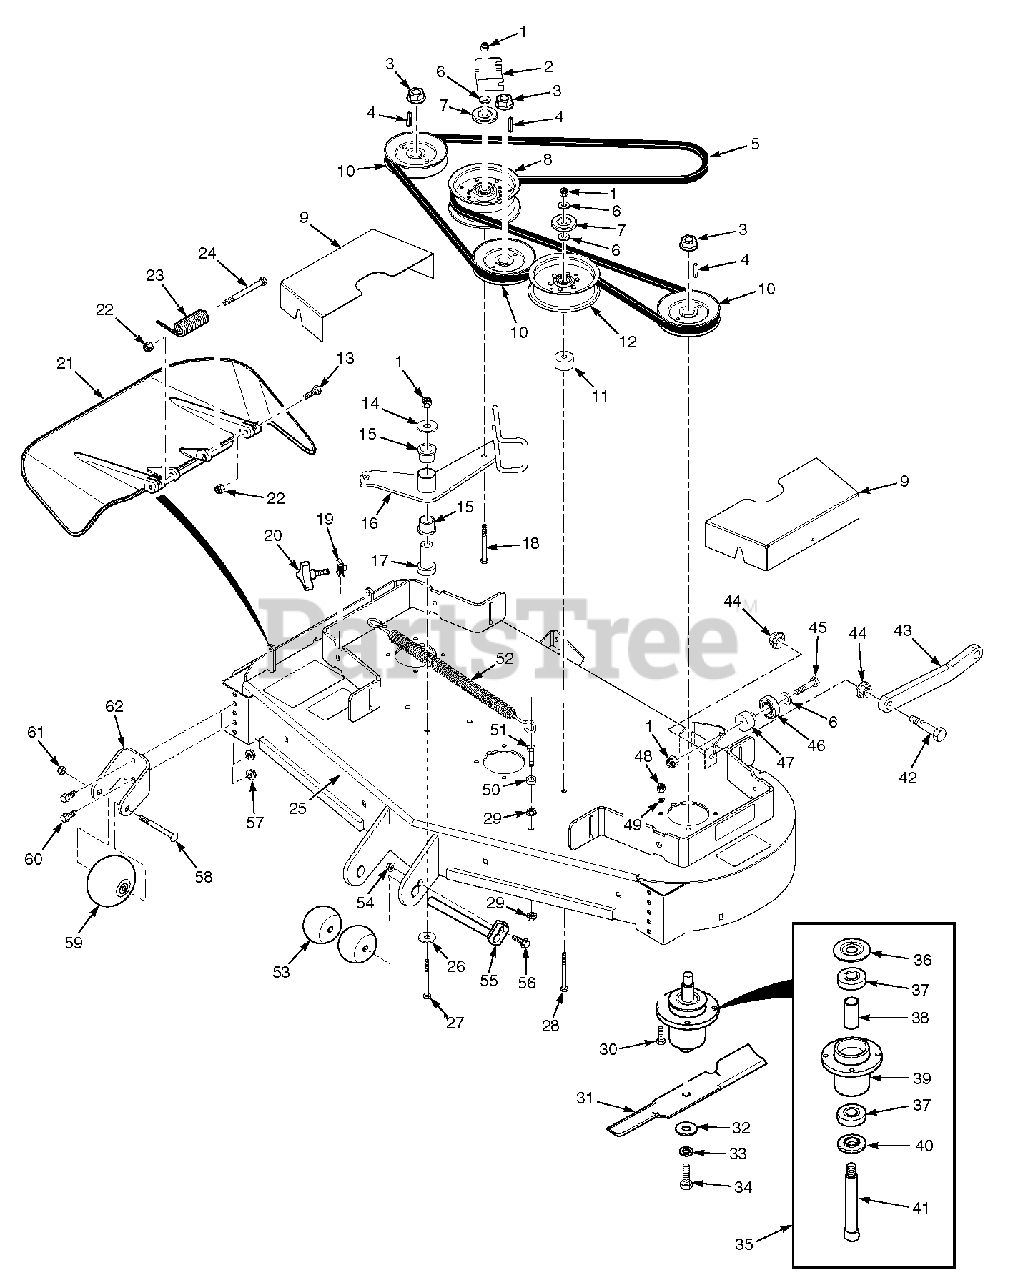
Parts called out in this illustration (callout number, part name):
1	Nut, Elastic Stop 3/8-16
2	Bracket, Belt Guide
3	Nut, 3/4-16 Spiral Lock
4	Key, 1/4 x 1/4 x 1-1/4"
5	Belt, Cutter Deck
6	Flatwasher, 3/8-.391 x .938 x .105
7	Dust Shield
8	Pulley, 5" Idler
9	Belt Cover
10	Pulley, 5.73" OD - 25mm Bore
11	Spacer
12	Pulley, 5" Idler
13	Bolt, Hex Head 5/16-18 x 1-3/4"
14	Flatwasher, 3/8-.406 x 1-1/2"
15	Bearing
16	Idler Arm (incl. item #15)
17	Pivot, Idler
18	Bolt, Hex Head 3/8-16 x 3-1/4"
19	U-Nut, 3/8-16
20	Knob w/Stud
21	Discharge Chute Assembly
22	Nut, Elastic Stop 5/16-18
23	Spring, Discharge Chute
24	Bolt, Hex Head 5/16-18 x 4-3/4"
25	Cutter Deck w/Decals, SMWZT-52
26	Flatwasher, 3/8-.406 x 2.25" x .188
27	Bolt, Hex Head 3/8-16 x 3-3/4"
28	Bolt, Hex Head 3/8-16 x 3-1/2"
29	Nut, Serrated Flange 3/8-16
30	Bolt, Hex Head 5/16-18 x 1-1/2" Gr.8
31	Cutter Blade, 18"
32	Flatwasher, 5/8-.688 x 1.75 x .134 HD
33	Lockwasher, 1/2 Spring
34	Bolt, Hex Head 5/8-11 x 1-1/2"
35	Spindle Assembly
36	Debris Shield
37	Bearing
38	Spacer
39	Spindle Housing Assembly
40	Protector, Bearing
41	Shaft, Spindle
42	Bolt, Hex Head 1/2-13 x 2"
43	Pusharm
44	Nut, Serrated Flange 1/2-13
45	Bolt, Hex Head 3/8-16 x 2-1/4"
46	Bearing
47	Spacer, Bearing
48	Nut, Elastic Stop 5/16-18
49	Lockwasher, 5/16 Spring
50	Spacer
51	Bolt, Hex Head 3/8-16 x 1-1/2 Gr.8
52	Spring, Idler
53	Wheel, Anti-Scalp
54	Nut, Serrated Flange 5/16-18
55	Shaft Weldment
56	Bolt, Hex Head 5/16-18 x 1"
57	Nut, Serrated Flange 3/8-16
58	Bolt, Carriage 3/8-16 x 4"
59	Wheel, Anti-Scalp
60	Bolt, Hex Head 3/8-16 x 1" Ser. Flg.
61	Nut, Center Lock 3/8-16
62	Bracket, Anti-Scalp
